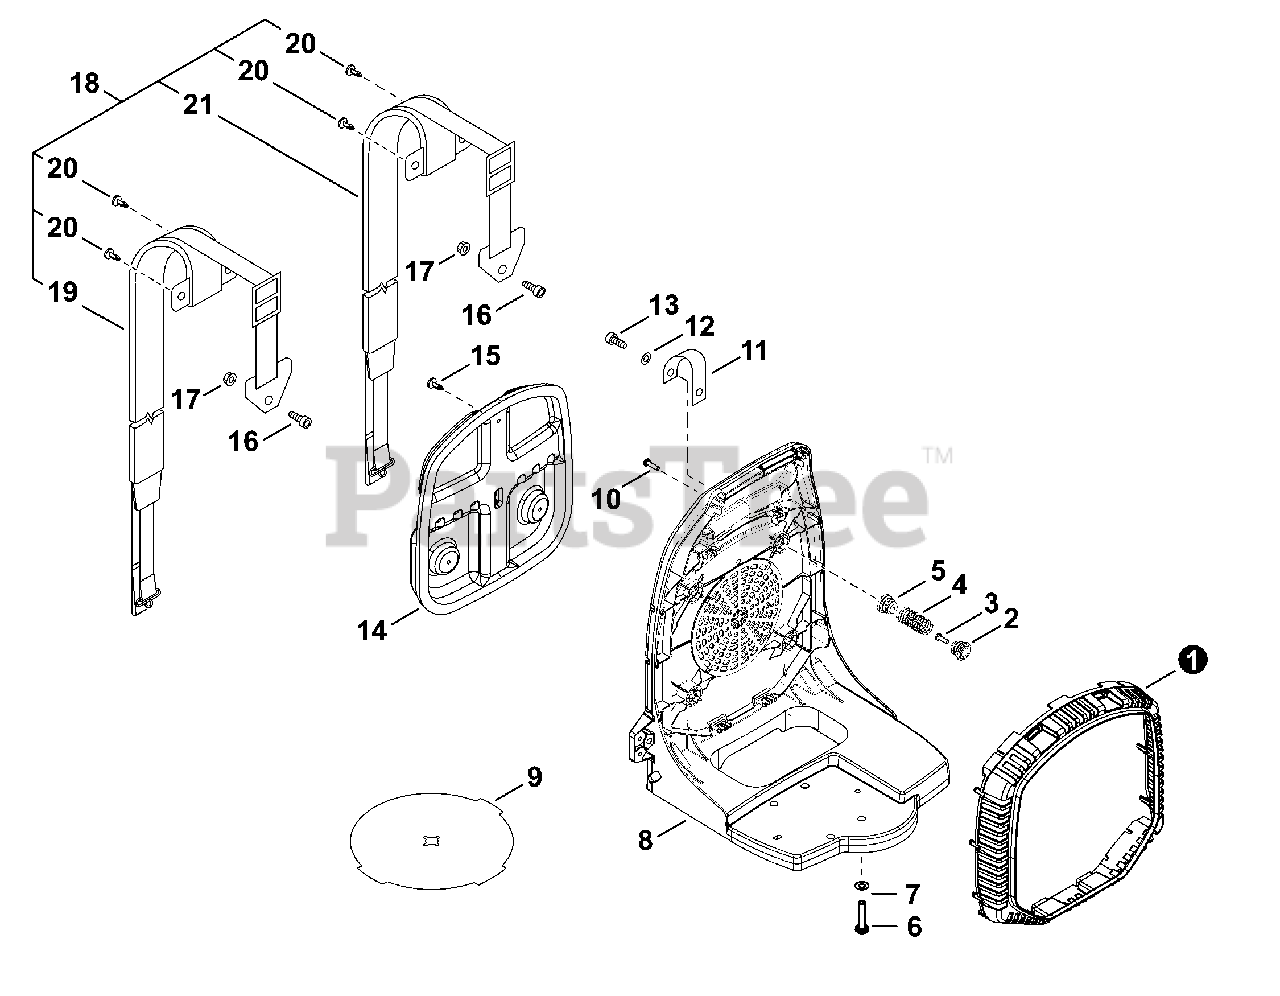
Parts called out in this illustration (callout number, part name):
1	GUARD, DEBRIS
2	HOLDER, SPRING
3	SCREW - 5×16
5	HOLDER, SPRING
6	SCREW - 5×25
7	WASHER - 5
8	FRAME, BACKPACK
9	INSERT, COLD WEATHER
10	SCREW - 5×20
11	STRAP, SAFETY
12	WASHER - 5
13	SCREW - 5×20
14	CUSHION, BACKPACK
16	SCREW - 5×30
17	LOCKNUT - 5
18	HARNESS KIT
19	HARNESS ASSY - LEFT
21	HARNESS ASSY - RIGHT
